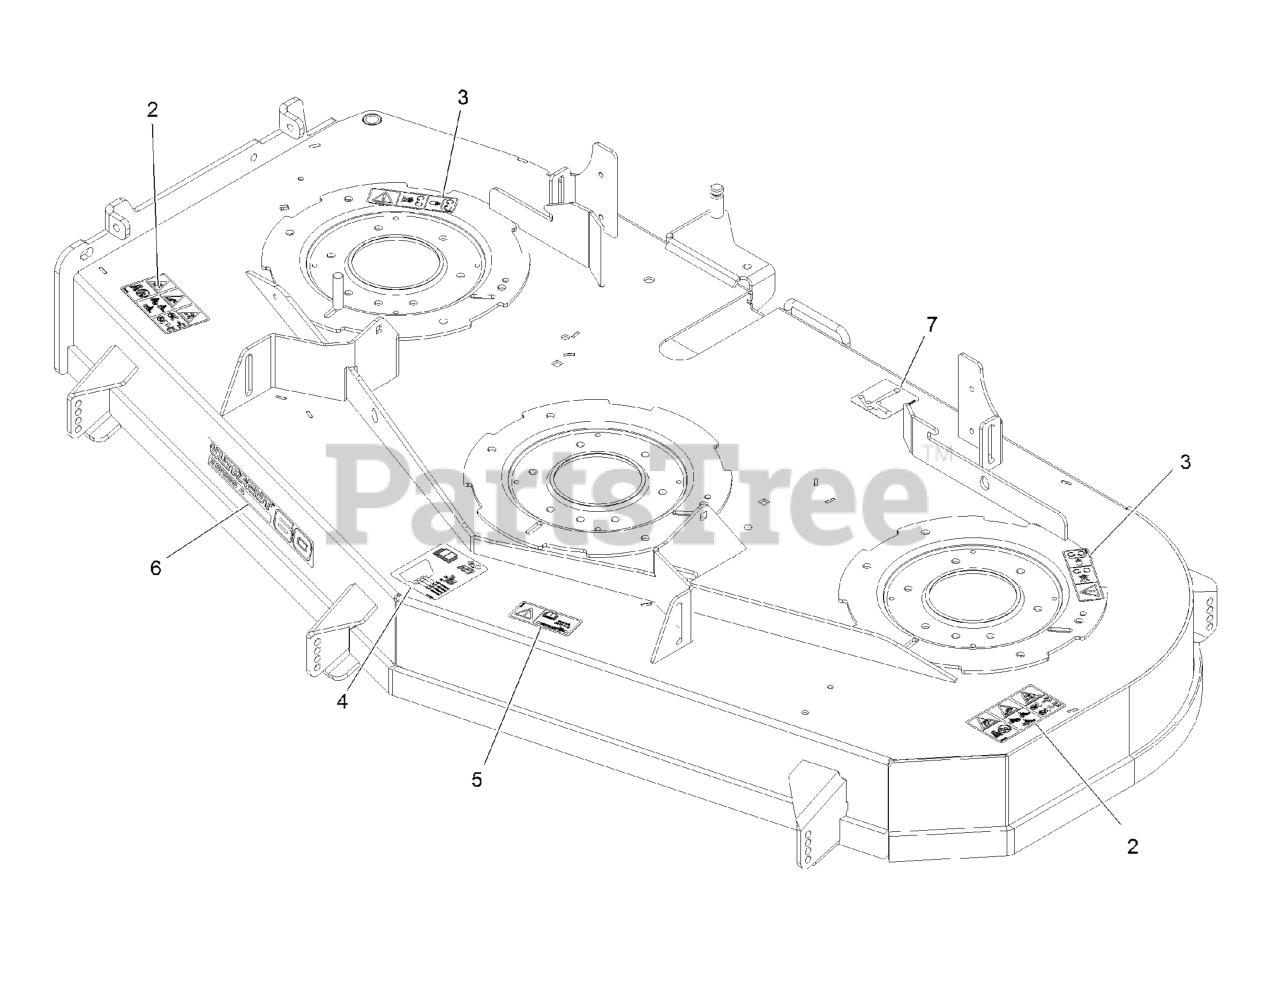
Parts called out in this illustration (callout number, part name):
2	DECAL-DANGER THROWN OBJECTS
3	DECAL-COVER, MISSING
4	DECAL-ROLLER, ANTI-SCALP
5	DECAL-TORQUE, BOLT
6	DECAL, 604
7	DECAL-ROUTING, BELT
